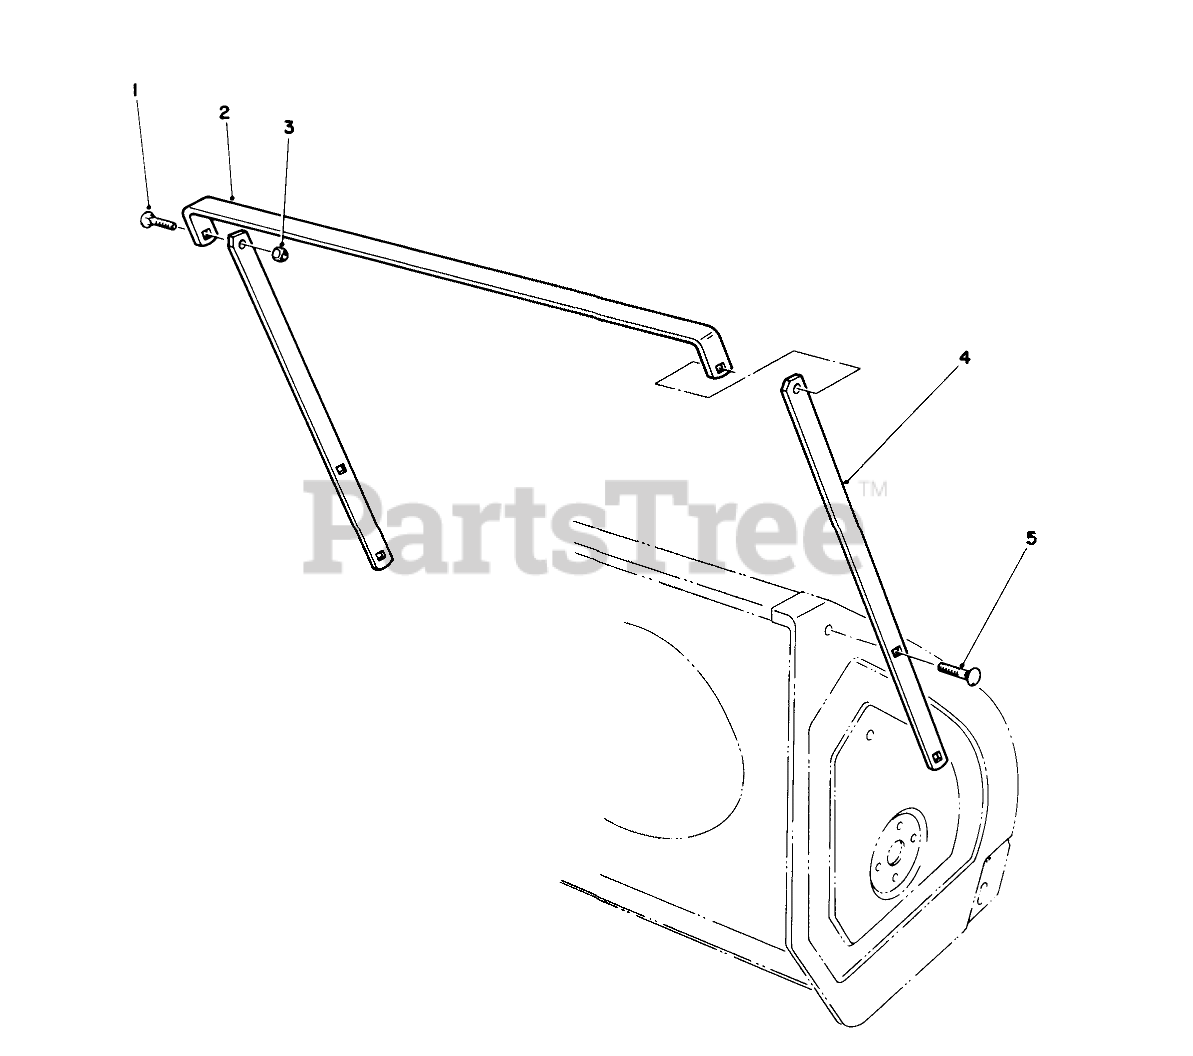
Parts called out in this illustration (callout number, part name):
1	SCREW-CARR
2	Breaker-Top (32")
3	NUT-LOCK, NI
4	Breaker-Side
5	BOLT-CARR
